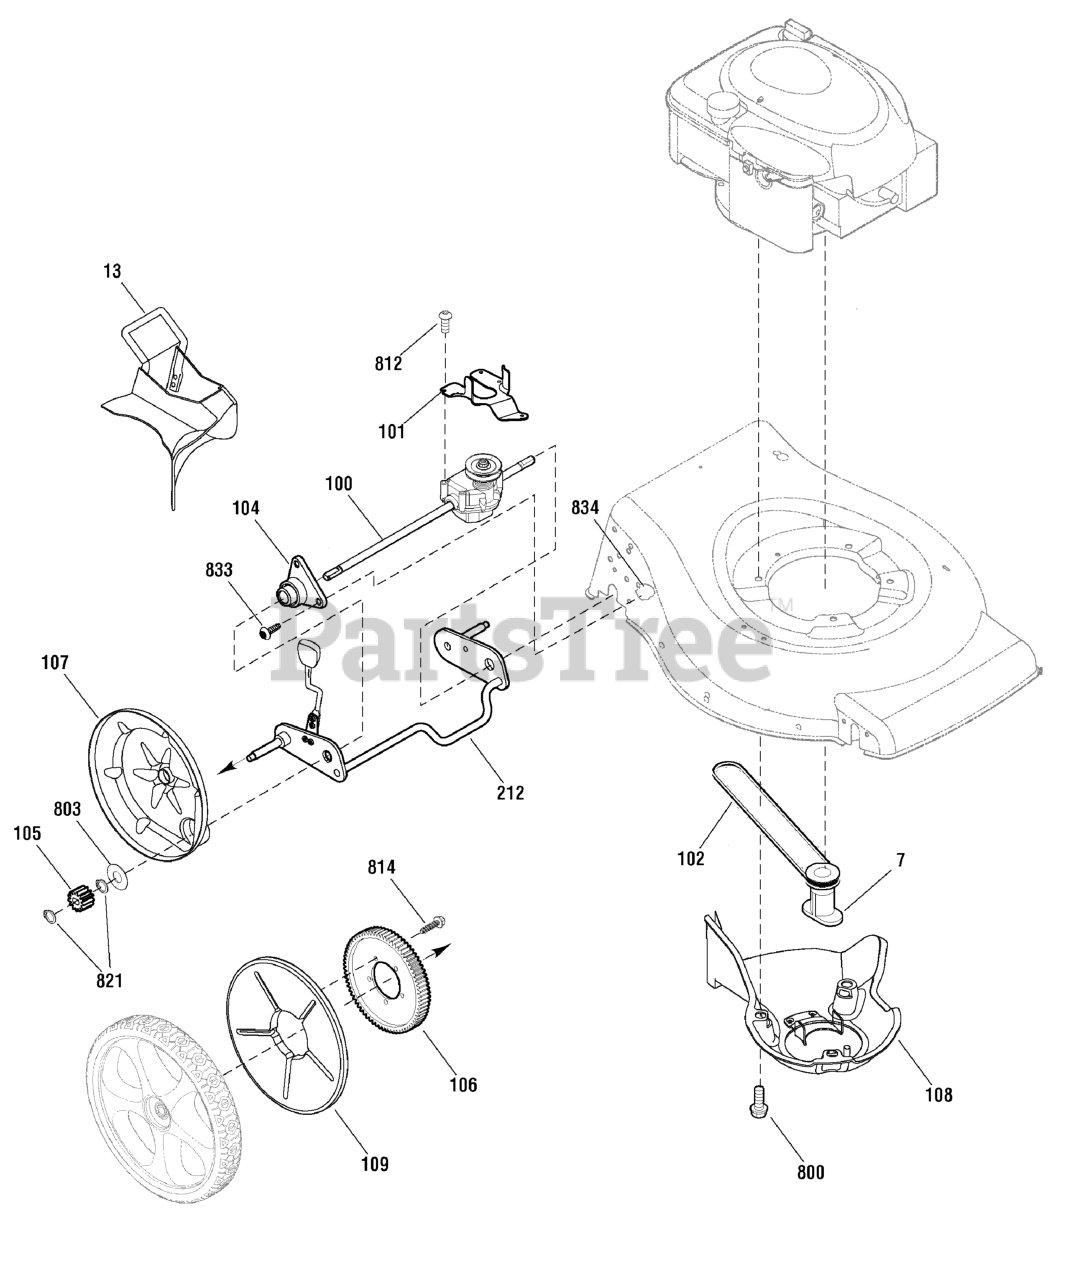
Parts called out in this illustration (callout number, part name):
7	BLADE ADAPTER ASSEMBLY
13	MULCH PLUG
100	TRANSMISSION
101	BELT GUIDE, Transmission
104	SLEEVE ASSEMBLY, Rear Axle
105	GEAR, Pinion
106	GEAR, Drive
107	DUST COVER
108	BELT COVER ASSEMBLY
109	COVER, Wheel
212	CROSSBAR ASSEMBLY, Rear
800	CAPSCREW, Hex Head, 3/8-16 x 1
803	WASHER, Thrust
812	SCREW, #10 x 1
814	SCREW, 1/4-15 x 3/4
821	RING, External Retaining
833	SCREW, Torx, 1/4-20 x 5/8
834	NUT, Flange Lock, 1/4-20
